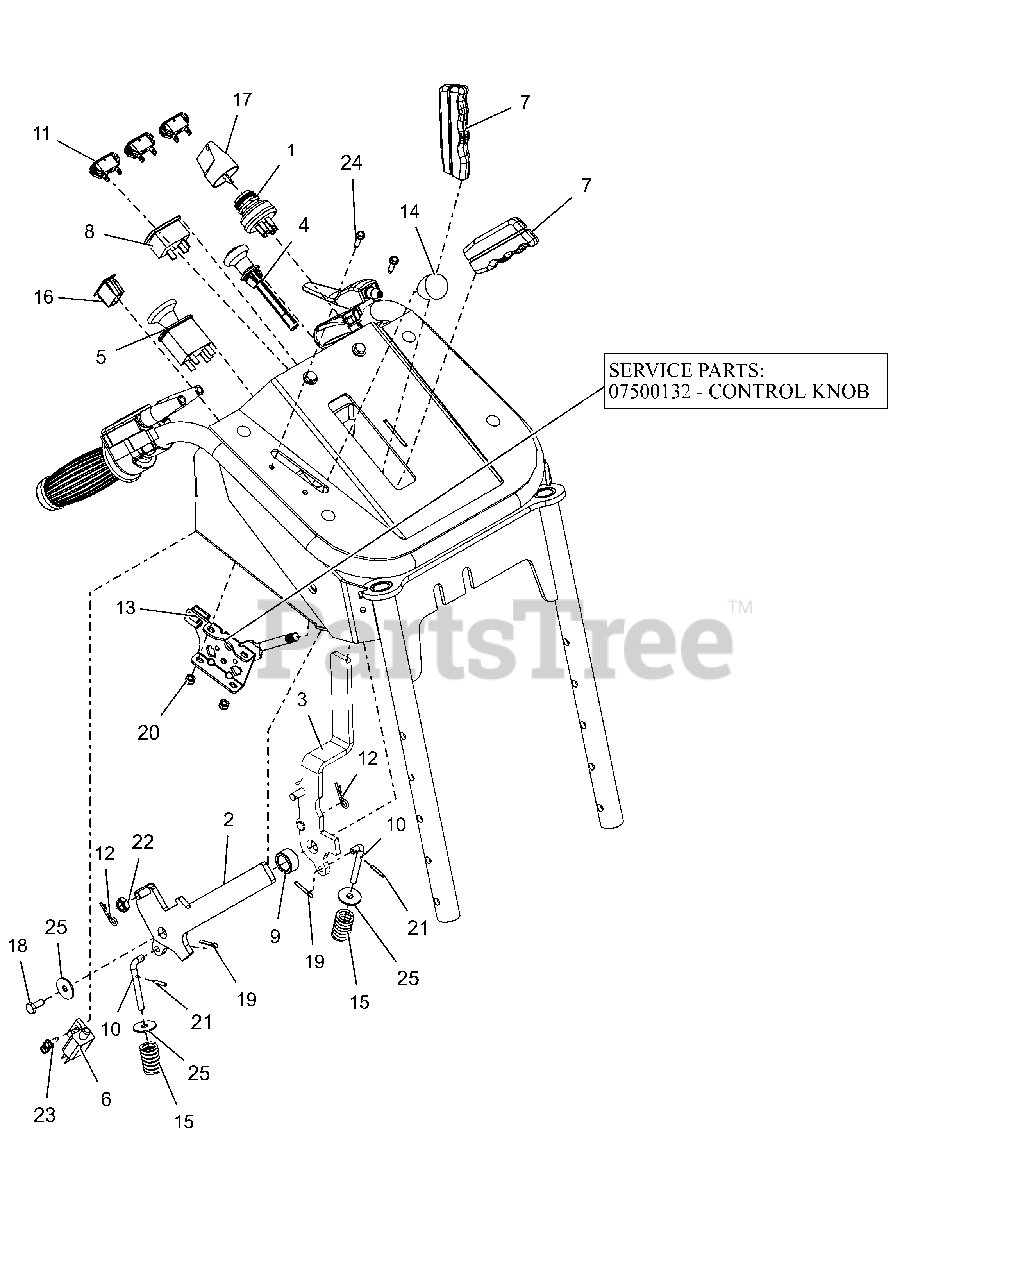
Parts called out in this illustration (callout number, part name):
1	SWITCH, IGNITION
2	WLDMT, BRAKE LEVER (BLACK)
3	WLDMT, STEERING LEVER (BLACK)
4	CABLE, CHOKE SNAP-IN 58"
5	SWITCH, CLUTCH
6	SWITCH- DOUBLE POLE N.O./N.O.
7	GRIP, PARKING BRAKE (YELLOW)
8	METER, HOUR W/MAINTENANCE
9	SPCR, .688 x 1.00 x .495
10	ROD, OVER CENTER BRAKE
11	LIGHT, INDICATOR (GREEN)
12	PIN-HAIR INT .08X.18X1.18 YWZC
13	CABLE, PROCONTROL THROTTLE 66"
13	KNOB-CONTROL-BLACK .38-16X.50
14	KNOB-CONTROL-BLACK .38-16X.50
15	SG-COMP .125X.781X1.250
16	SWITCH,BLANK
17	KEY, W/ SHIELD
18	@BLT-HEX .25-20X.63 GR5 YWZC
19	PIN,CTR .12X.75EXTPRSQCT ZC120
20	@NUT-LK-NYL 10-24 W/INSRT YWZC
21	PIN-ROLL .125X.75
22	NUT-HEX-JAM .375-16 YWZC
23	@SCR-TAP 10-24X.50 HWH TR YWZC
24	SCR-TAP 10-24X.75 HWH TR YWZC
25	WSHR-FL-STL .281X1.000X.063
